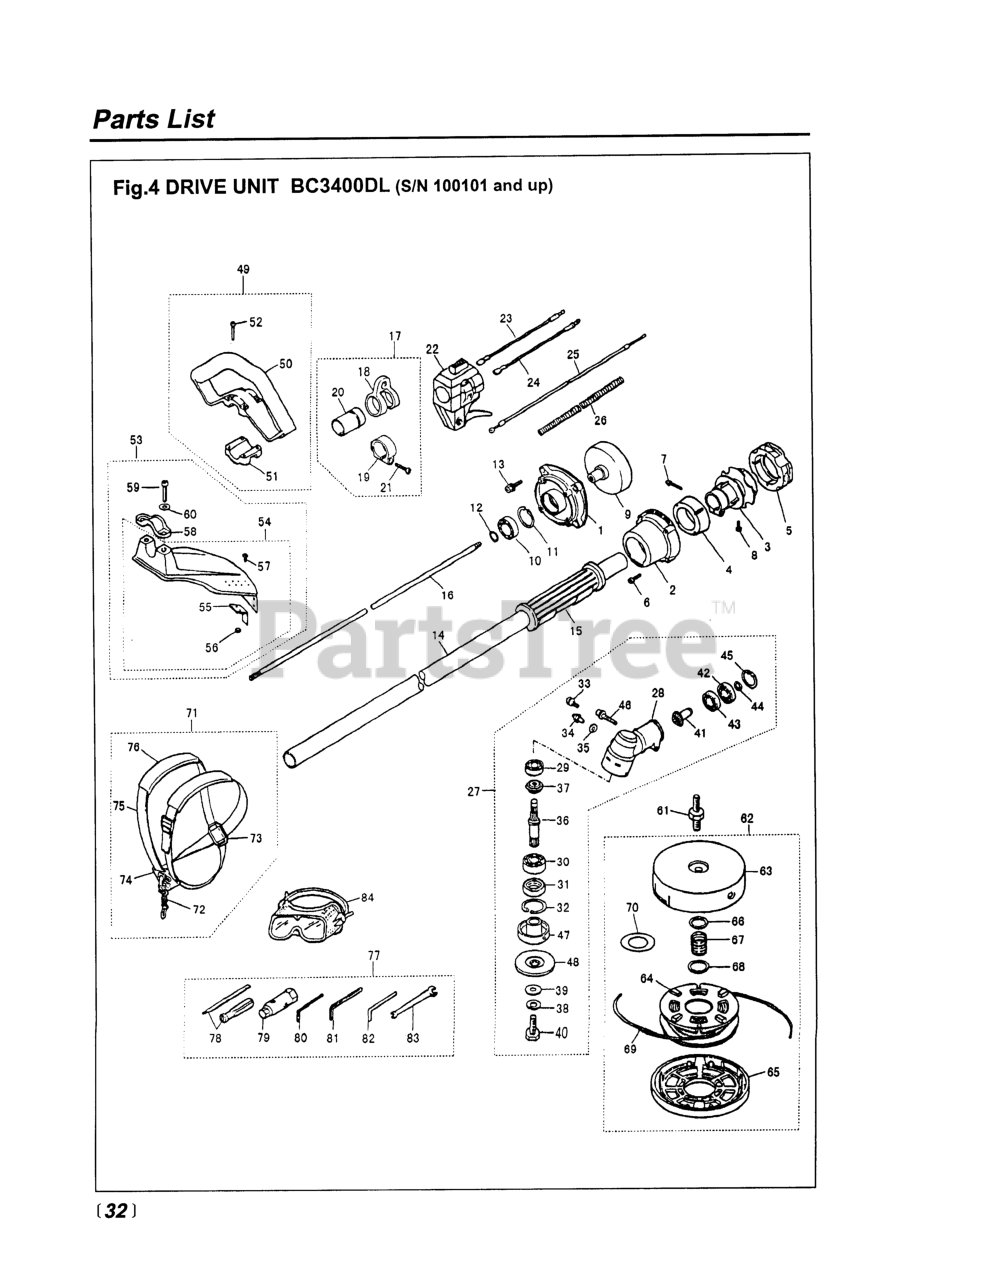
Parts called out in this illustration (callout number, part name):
1	HOUSING
2	CAP
3	JOINT
4	ABSORBER-F
5	ABSORBER-R
6	BOLT, M5 X 30
7	BOLT, M6 x 30
8	BOLT, M5 X 10
10	BEARING
11	RING, SNAP, M35 X 1.5
12	RING, SNAP, M15 X 1.0
13	BOLT, M6 x 20
14	PIPE COMP.
15	GRIP (RPLS 3577-32140 & 3220-
16	SHAFT, DRIVE (REPLACES -12210)
17	HANGER ASSEMBLY
18	HANGER
19	CLAMP
21	SCREW, M5 x 25
23	CORD (A), BLACK
24	CORD (B), RED
25	CABLE COMP (RPLS 1633-83100)
26	TUBE
28	GEARCASE (RPLS -13113)
29	BEARING (RPLS T3403-13510)
31	SEAL, OIL
32	RING, SNAP, M32 x 1.2
33	BOLT, M5 X 10
34	FITTING, GREASE
35	WASHER, M6 X .8
36	SHAFT
37	GEAR, BEVEL
38	WASHER (RPLS 3180-13270)
39	WASHER, M8 x 2.3 (RPLS -20823)
40	BOLT, LH
41	PINION
43	BEARING (RPLS T3403-13510)
44	RING, SNAP
45	RING, SNAP, M26 X 1.2
46	BOLT, M6 x 1.35
47	HOLDER (A)
48	HOLDER (B)
49	HANDLE ASSEMBLY
50	HANDLE
51	CLAMP
52	SCREW, M5 x 35
53	GUARD ASSY (RPLS -24001)
54	GUARD COMP
55	BLADE
56	NUT
57	SCREW, M5 x 12
58	CLAMP
59	BOLT, M6 x 1.30
60	WASHER, M6 X 15
61	SHAFT (RPLS 3274-99120)
62	6
63	CASE (USE -99112)
65	COVER
66	PLATE, LARGE
68	PLATE, SMALL
69	CORD
70	SPACER
74	HANGER COMP.
75	BAND (NOT SOLD SEPARATELY)
76	PROTECTOR
77	TOOL SET
78	SCREWDRIVER
80	WRENCH (TOOL)
81	WRENCH (TOOL)
82	BAR
83	SPANNER, 8 X 10 (RPLS 2540- )
